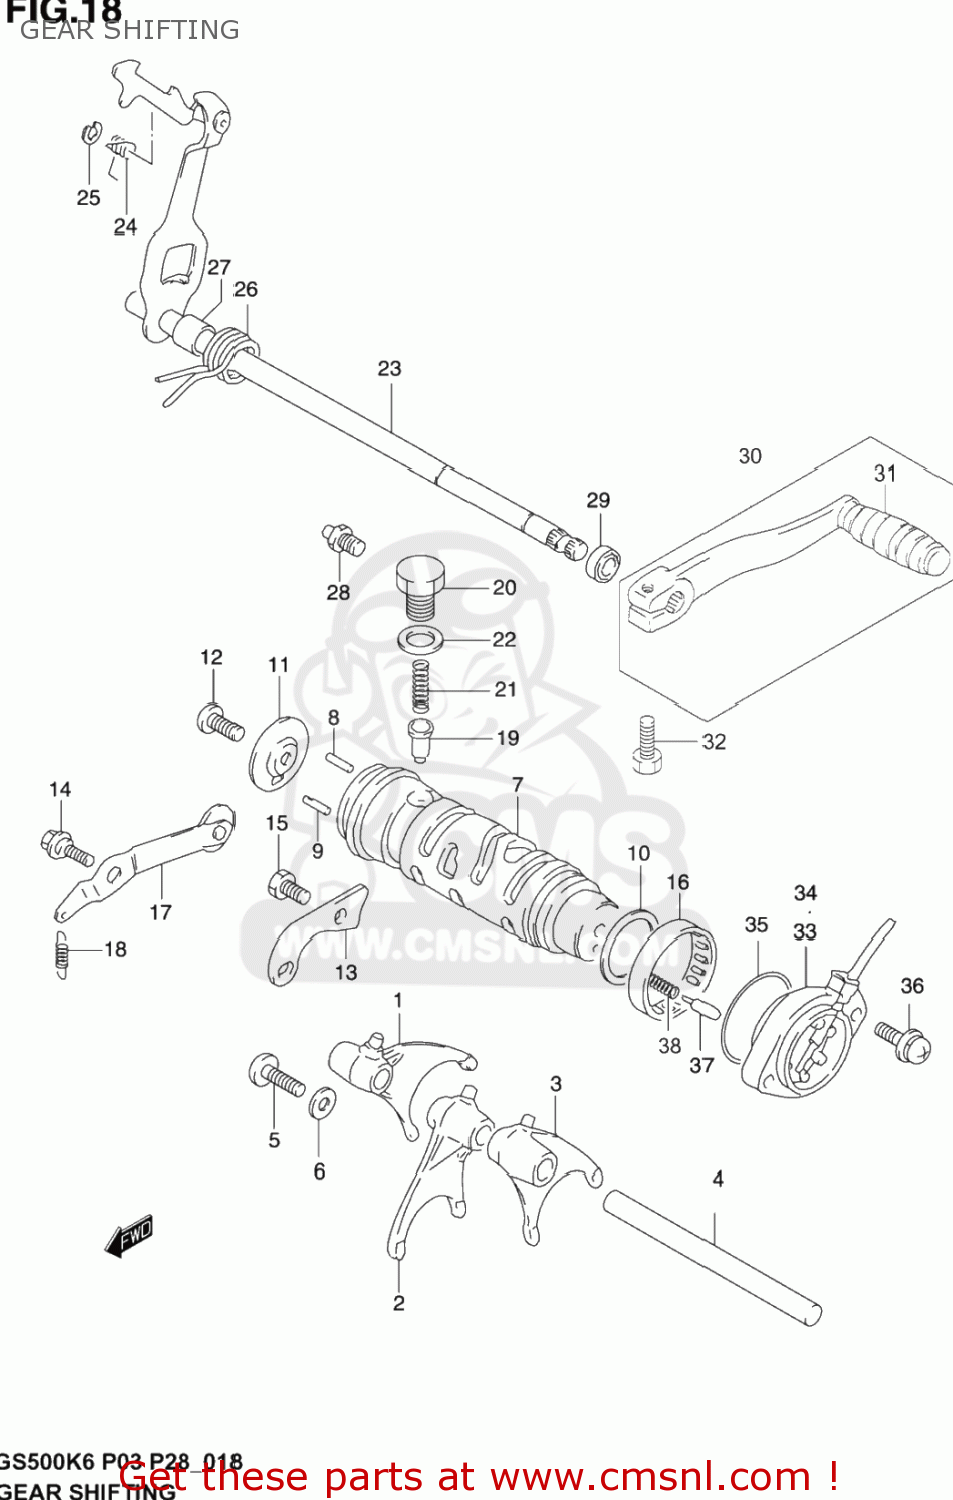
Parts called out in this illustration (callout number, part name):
1	FORK,GEAR SHIFT NO.1
2	FORK,GEAR SHIFT NO.2
3	FORK,GEAR SHIFT NO.2
4	SHAFT,GEAR SHIFT FORK
5	SCREW(6X8)
6	WASHER
7	CAM,GEAR SHIFT
8	PIN(4X18.5)
9	PIN
10	SHIM(26X32.5X0.3)
11	RETAINER,GEAR SHIFT CAM DR PIN
12	SCREW 6X16
13	GUIDE,GEAR SHIFT CAM
14	BOLT(6X14.6)
15	BOLT(6X16)
16	BEARING(40X47X12)
17	STOPPER,GEAR SHIFT CAM NO.1
18	SPRING
19	STOPPER,GEAR SHIFT CAM NO.2
20	HOLDER,GEAR SHIFT CAM STOP SPR
21	SPRING
22	GASKET(13.8X18.8X4.8) (NAS)
23	SHAFT,GEAR SHIFT
24	SPRING
25	E-RING
26	SPRING
27	SPACER(12X20X15.3)
28	STOPPER,GEAR SHIFT ARM
29	OIL SEAL
30	LEVER ASSY,GEAR SHIFT
31	RUBBER,GEAR SHIFT PEDAL
32	BOLT
33	BASE ASSY,NEUTRAL SW TERMINAL
34	BASE ASSY,GEAR SHIFT TERMINAL
35	O RING(D:2.4,ID:25.7)
36	SCREW
37	PIN(5X15.5)
38	SPRING
